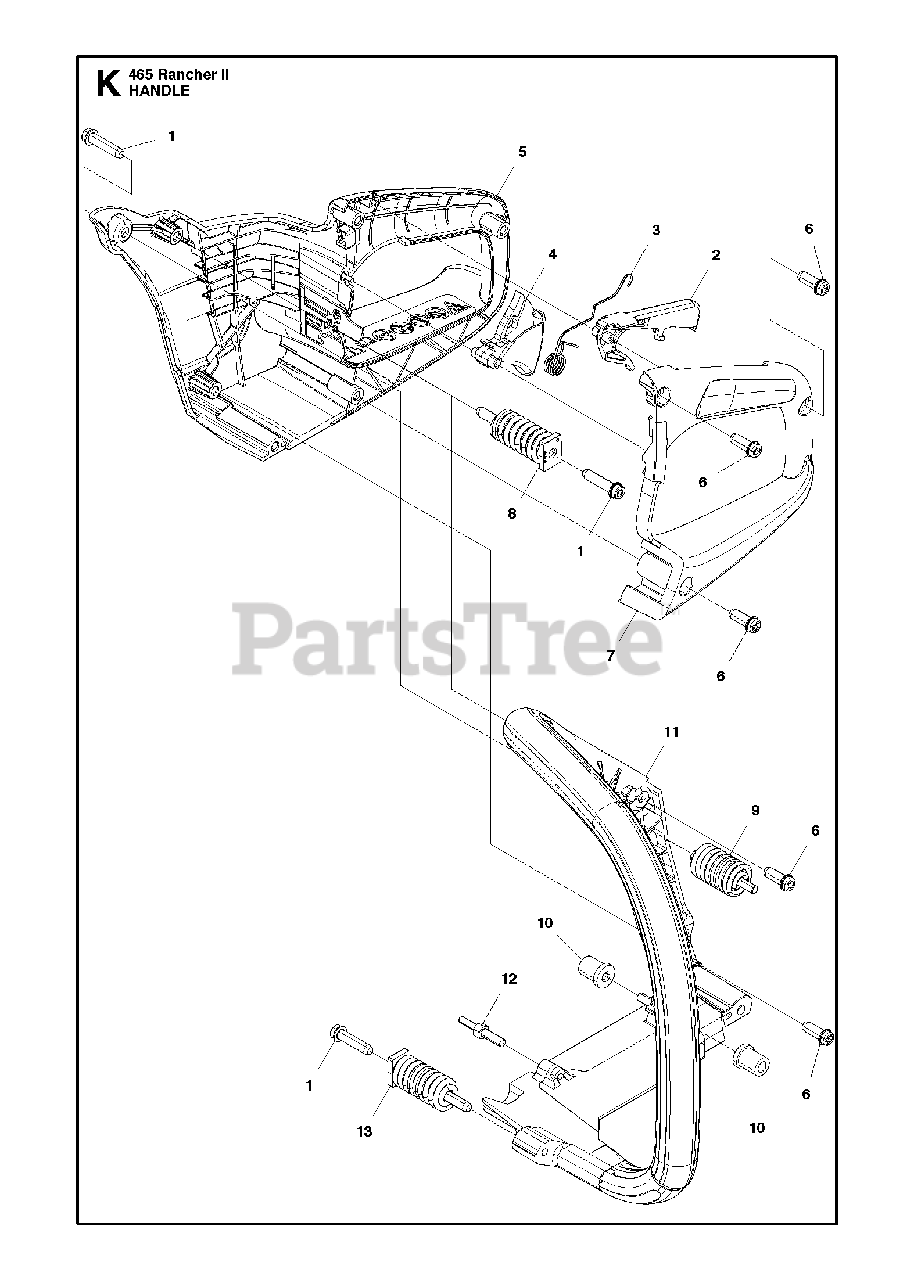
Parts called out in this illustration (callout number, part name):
2	THROTTLE LOCK
4	THROTTLE TRIGGER
5	REAR HANDLE
7	CAP - LEFT SIDE HANDLE
8	ANTIVIBRATION ELEMENT
9	ANTIVIBRATION ELEMENT
10	MOVEMENT LIMITER
11	FRONT HANDLE
13	ANTIVIBRATION ELEMENT
